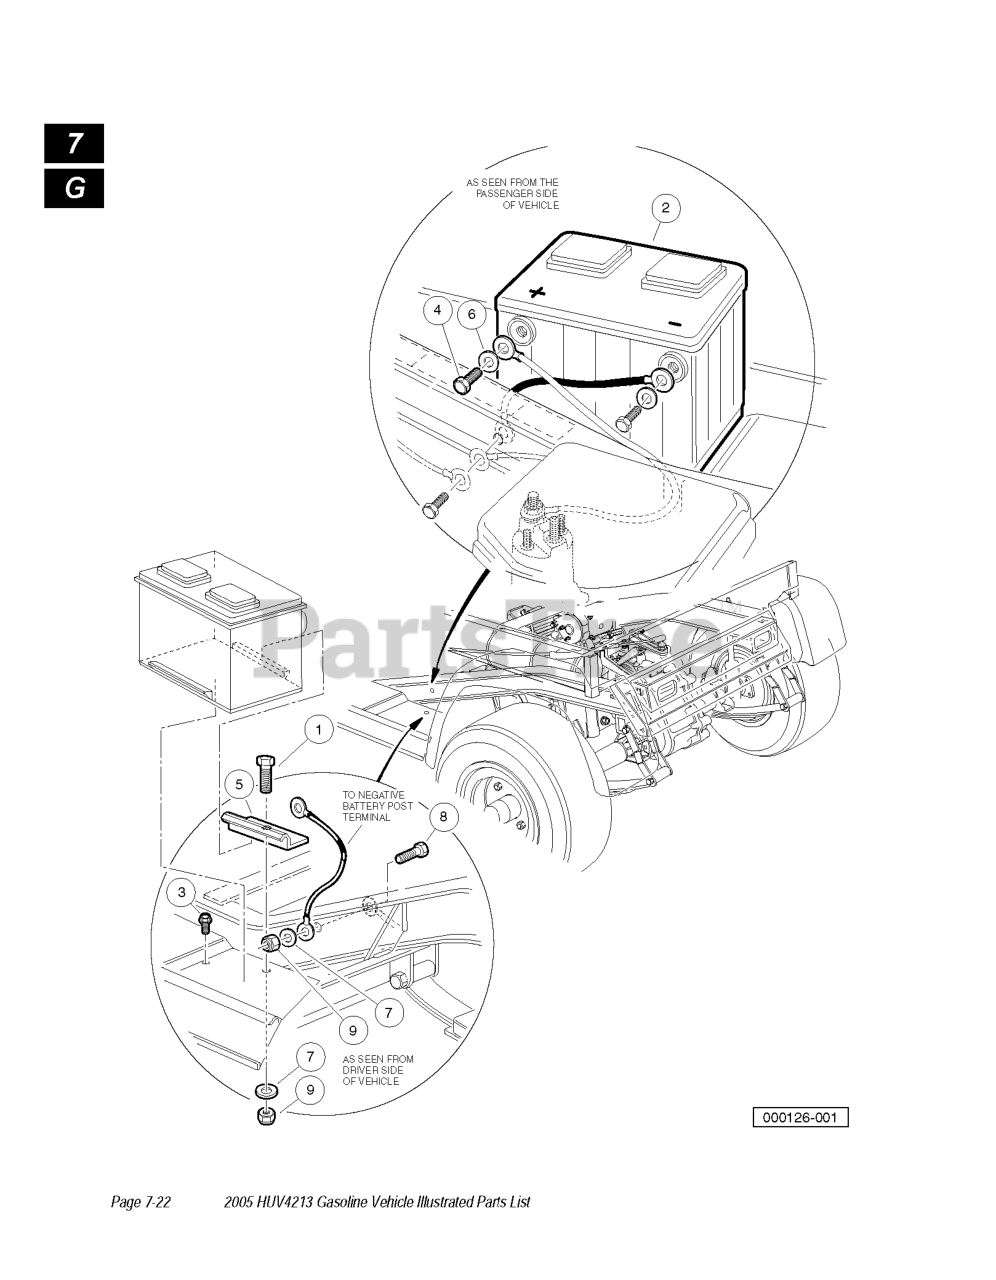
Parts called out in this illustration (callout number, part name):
1	SCREW HEX CAP
2	BATTERY, 12 VOLT
5	CLAMP - BATTERY
6	LOCKWASHER, 3/8 STAINLESS STL
7	WASHER, 5/16 TYPE A FLAT
8	SCREW, 5/16-18 X .75 HX HD CAP
9	LOCKNUT, 5/16-18 NYLON INSERT
